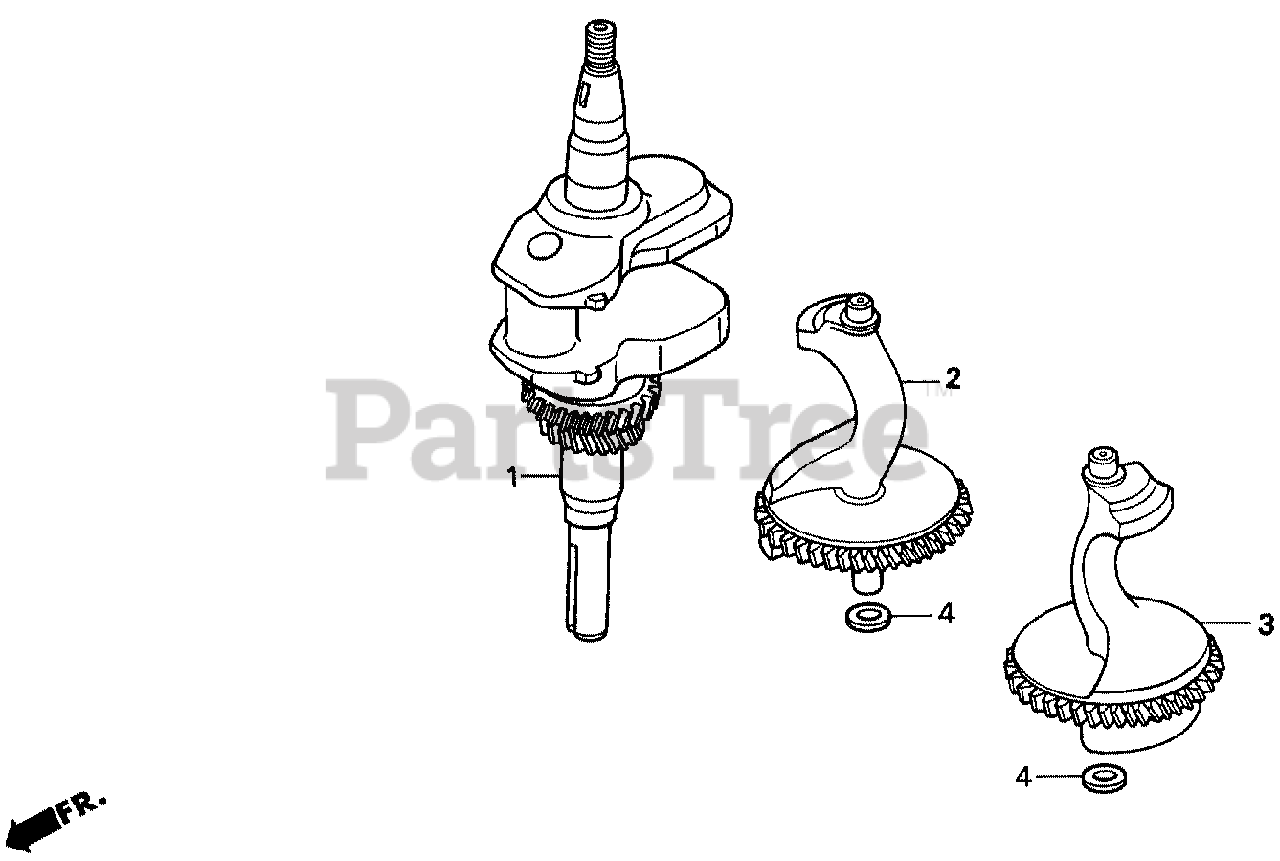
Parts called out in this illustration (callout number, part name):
1	CRANKSHAFT COMP.
2	WEIGHT A, BALANCER
3	WEIGHT B, BALANCER
4	WASHER, THRUST (14MM)
